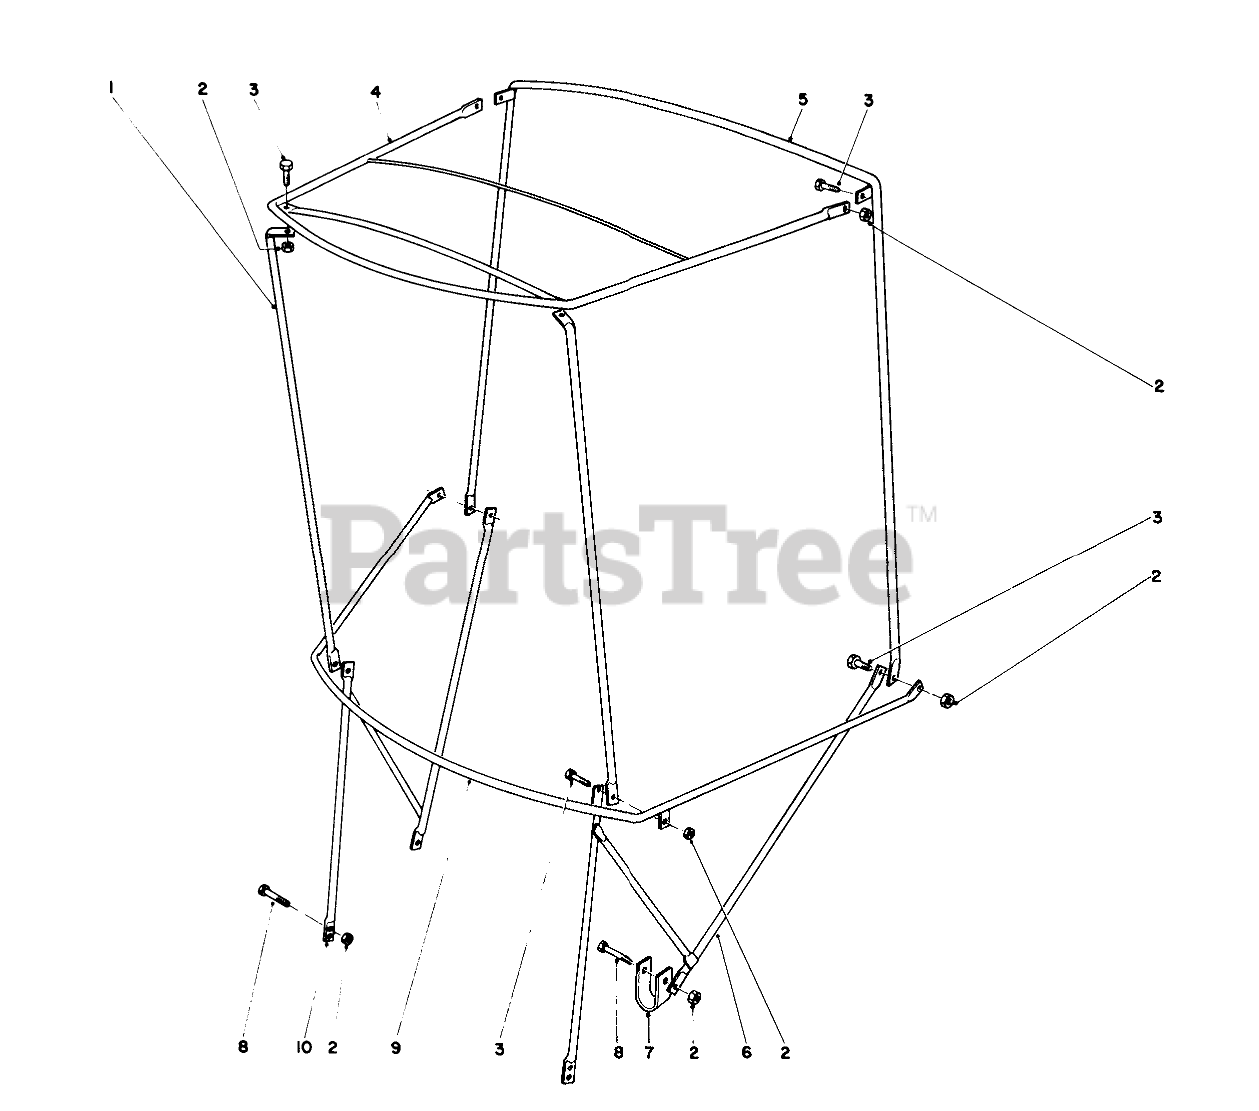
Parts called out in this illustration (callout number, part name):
2	NUT-LOCK
3	Bolt
4	FRAME-TOP
5	BOW-VERTICAL, REAR
6	ATTACHING BRKT L
7	U CLAMP
8	SCREW-HH
9	BOW-CURVED
10	Attaching Bracket R.H.
